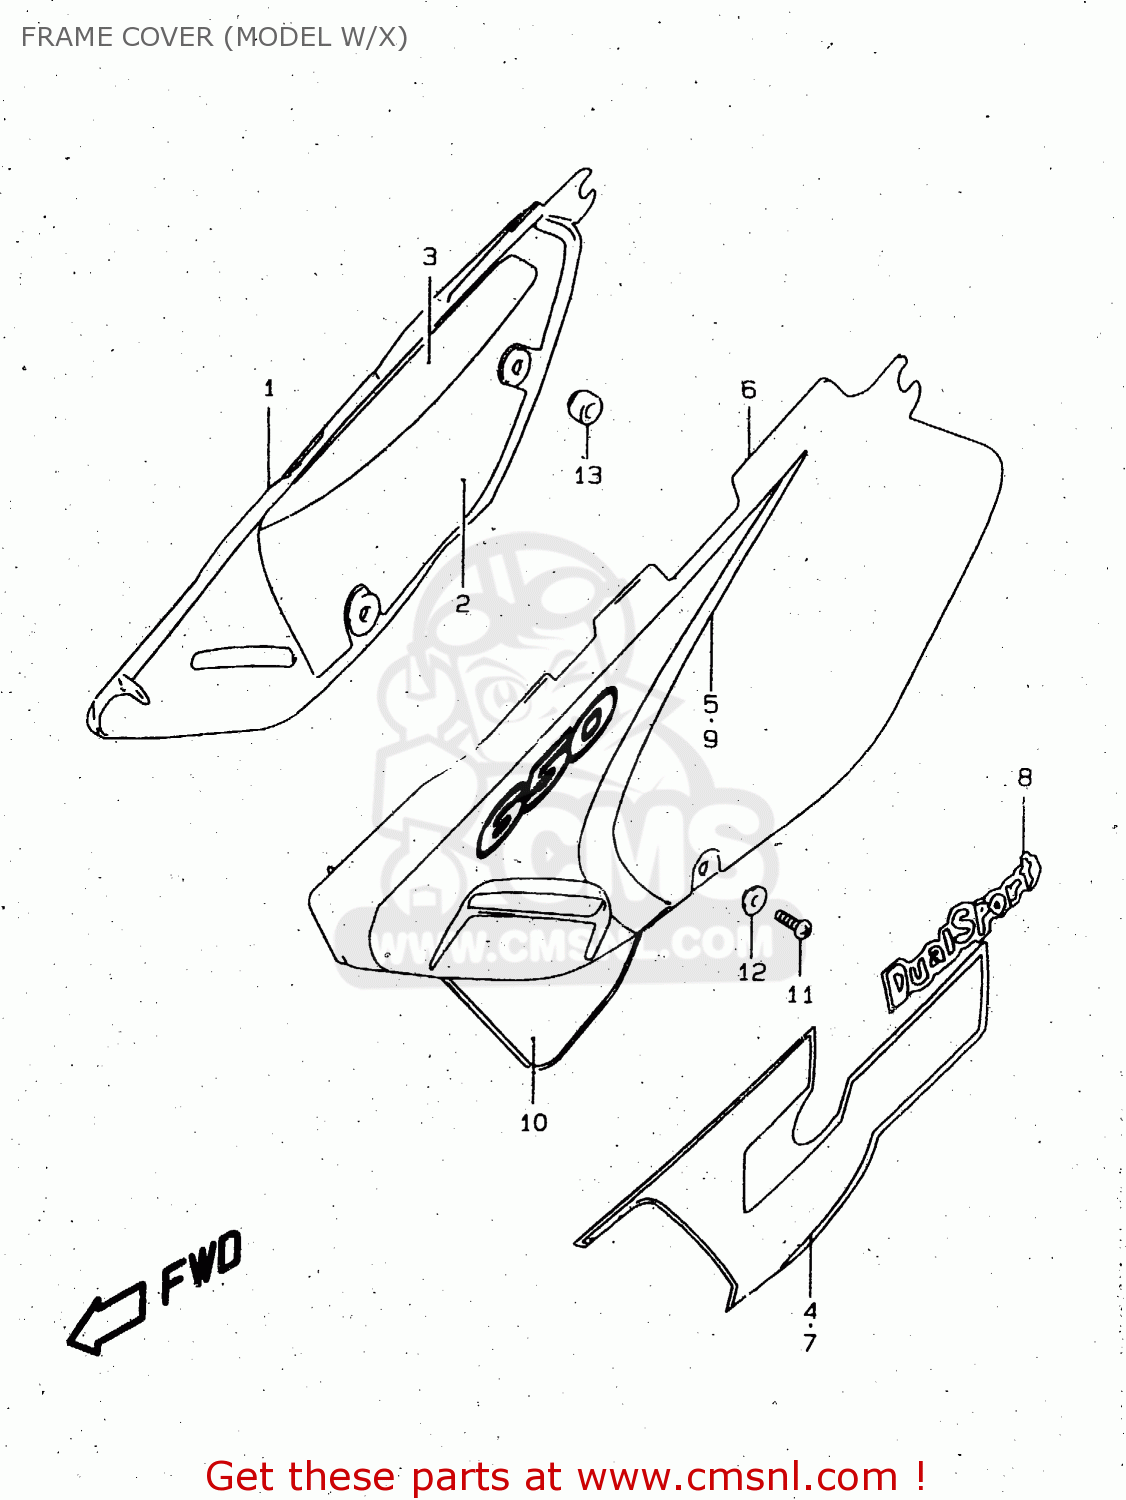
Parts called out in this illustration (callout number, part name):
1	COVER,FRAME,RIGHT
2	SHIELD,FRAME COVER,R NO.1
3	SHIELD,FRAME COVER,R NO.2
4	TAPE,FRAME COVER,RIGHT
5	TAPE,FRAME COVER,R
6	COVER,FRAME,LEFT
7	TAPE,FRAME COVER,LEFT
8	EMBLEM,FRAME COVER
9	TAPE,FRAME COVER,L
10	TAPE,LWR
11	SCREW
12	WASHER
13	CUSHION
